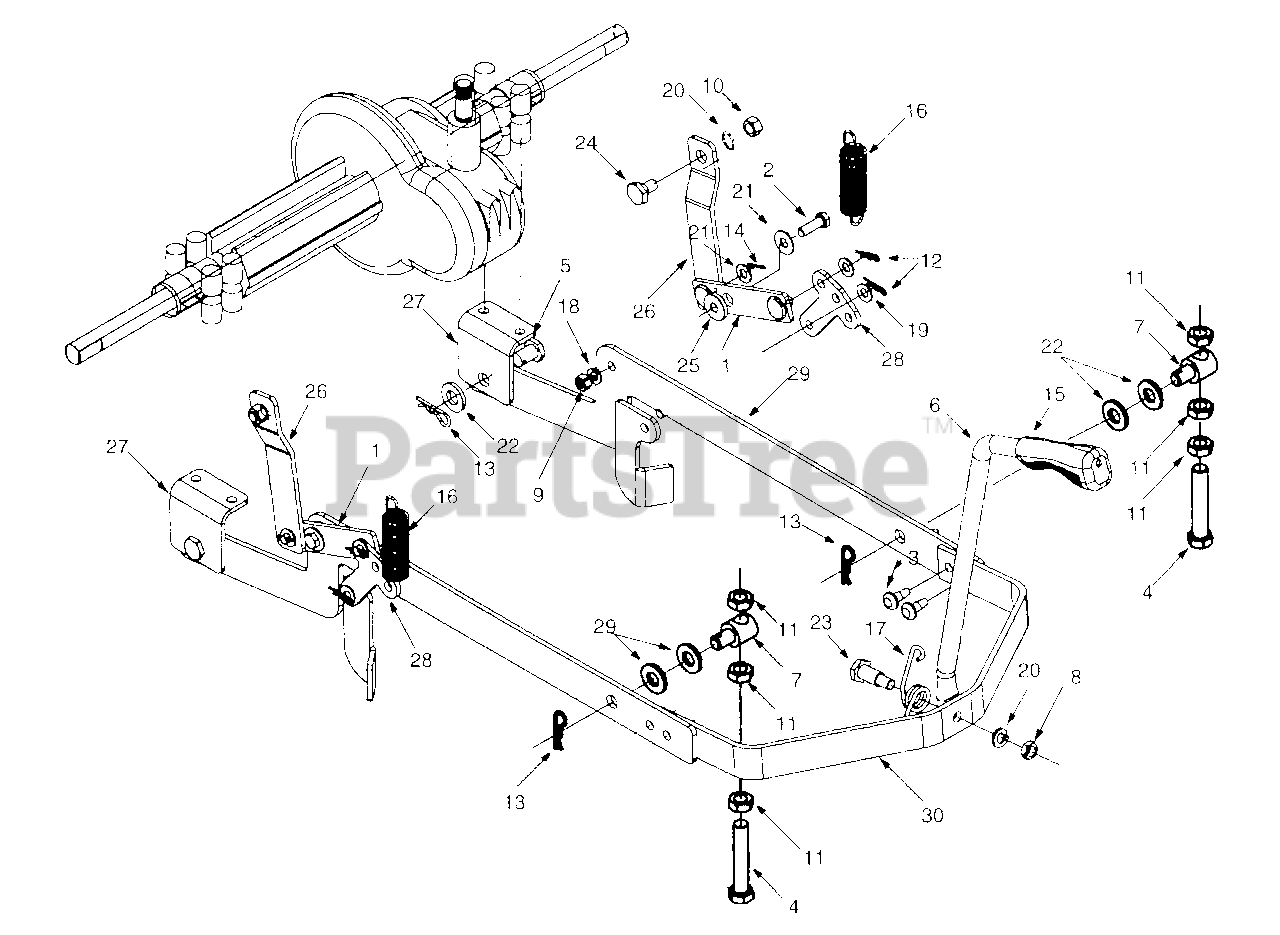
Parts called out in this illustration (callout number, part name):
4	Hex Bolt 1/2-13 X 2.75 Gr.5 Special
5	Lift Bracket Pin
7	Ferrule
8	Jam Nut 3/8-16 Gr. 5
9	Hex Nut 5/16-18
10	Hex Cent. Lock Nut 3/8-16
11	Hex Jam Nut 1/2-13 Gr.5
12	Cotter Pin
13	Cotter Pin
14	Cotter Pin
15	Handle Grip
16	Extension Spring
17	Torsion Spring
18	Lock Washer 5/16
19	Flat Washer .385 I.D. x .620 O.D.
20	Lock Washer
21	Flat Washer 5/16
23	Shoulder Screw
24	Shoulder Screw
25	Shoulder Spacer
29	Flat Washer .526 1.D. x 1.262 O.D.
